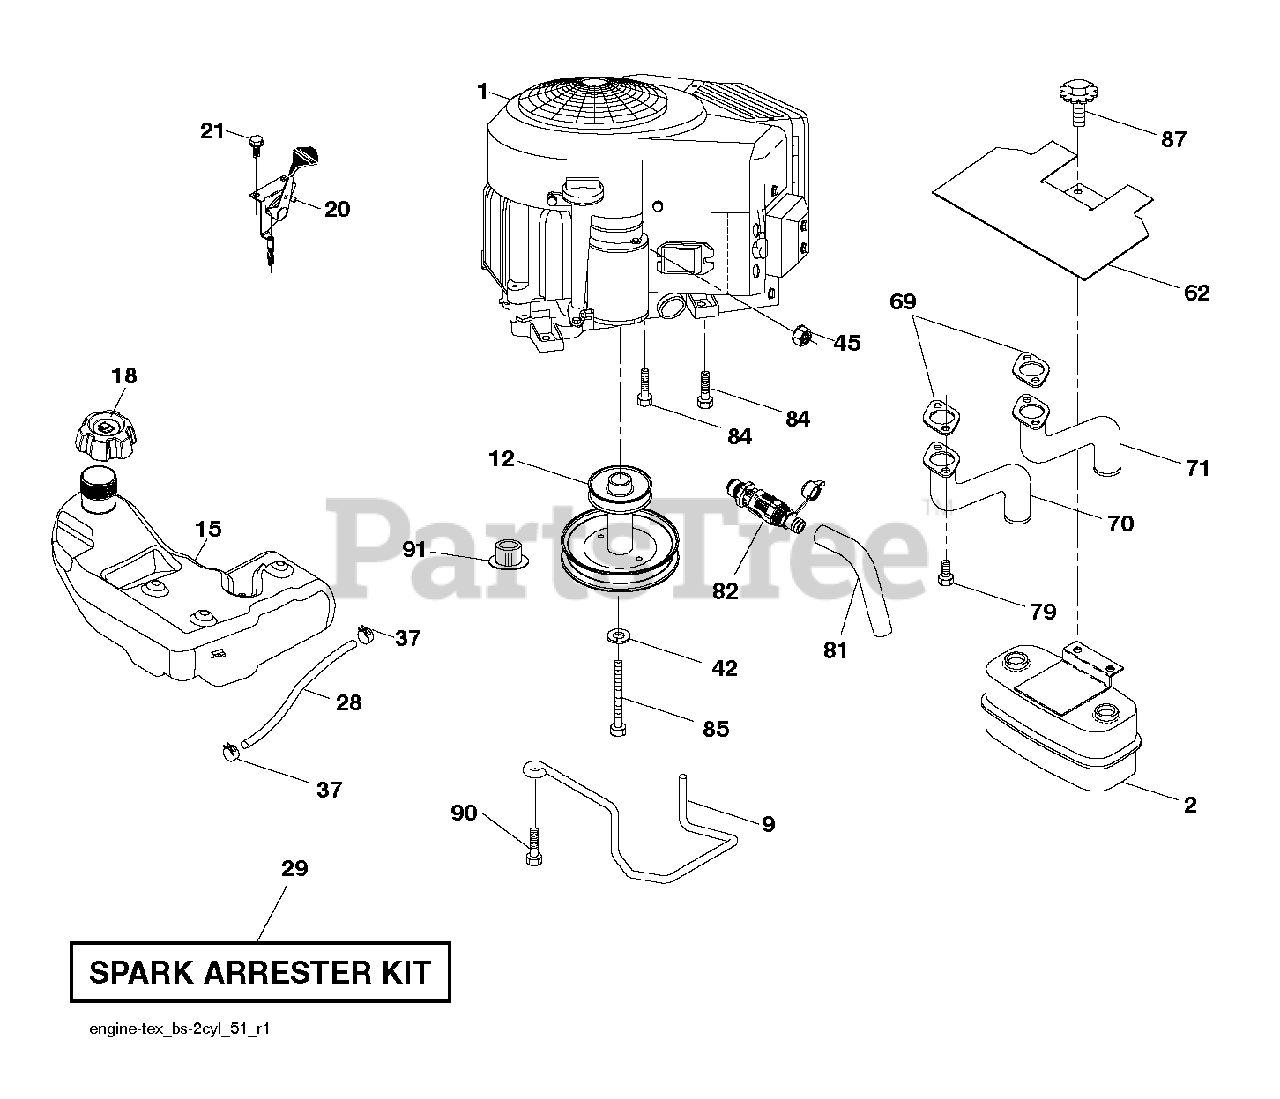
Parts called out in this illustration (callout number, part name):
2	MUFFLER.TWIN.CYL.LOW.TONE
9	KEEPER.BELT.ENGINE.4.2
12	PULLEY ENGINE
15	TANK.ASSY.3.GAL.EPA
18	CAP ASM.FL.RTCHT.3"GRY.E10
21	SCREW.#10 X 0.750.BOS (2 2)
28	LINE.FUEL.64"REAR.EMIS
29	KIT.SPARK ARRESTOR(392390 B&S)
37	HOSE CLAMP
42	LOCKWASHER
45	NUT
62	SHIELD.HEAT.MUFFLER
69	GASKET.MUFFLER
70	RP.EXHAUST.TUBE.LH.BS/TWIN
71	RP.EXHAUST.TUBE.RH.BS/TWIN
79	SCREW.SOCKET.HEAD.5/16-18
81	TUBE, DRAIN OIL ASM.
82	VALUE.OIL.DRAIN
84	SCREW.3/8-16
85	BOLT HEX 7/16-20X4-1/4"
87	BOLT, 5/16-18 X 1 3/4
90	SCREW 3/8-16X1
91	BUSHING.1.375OD
